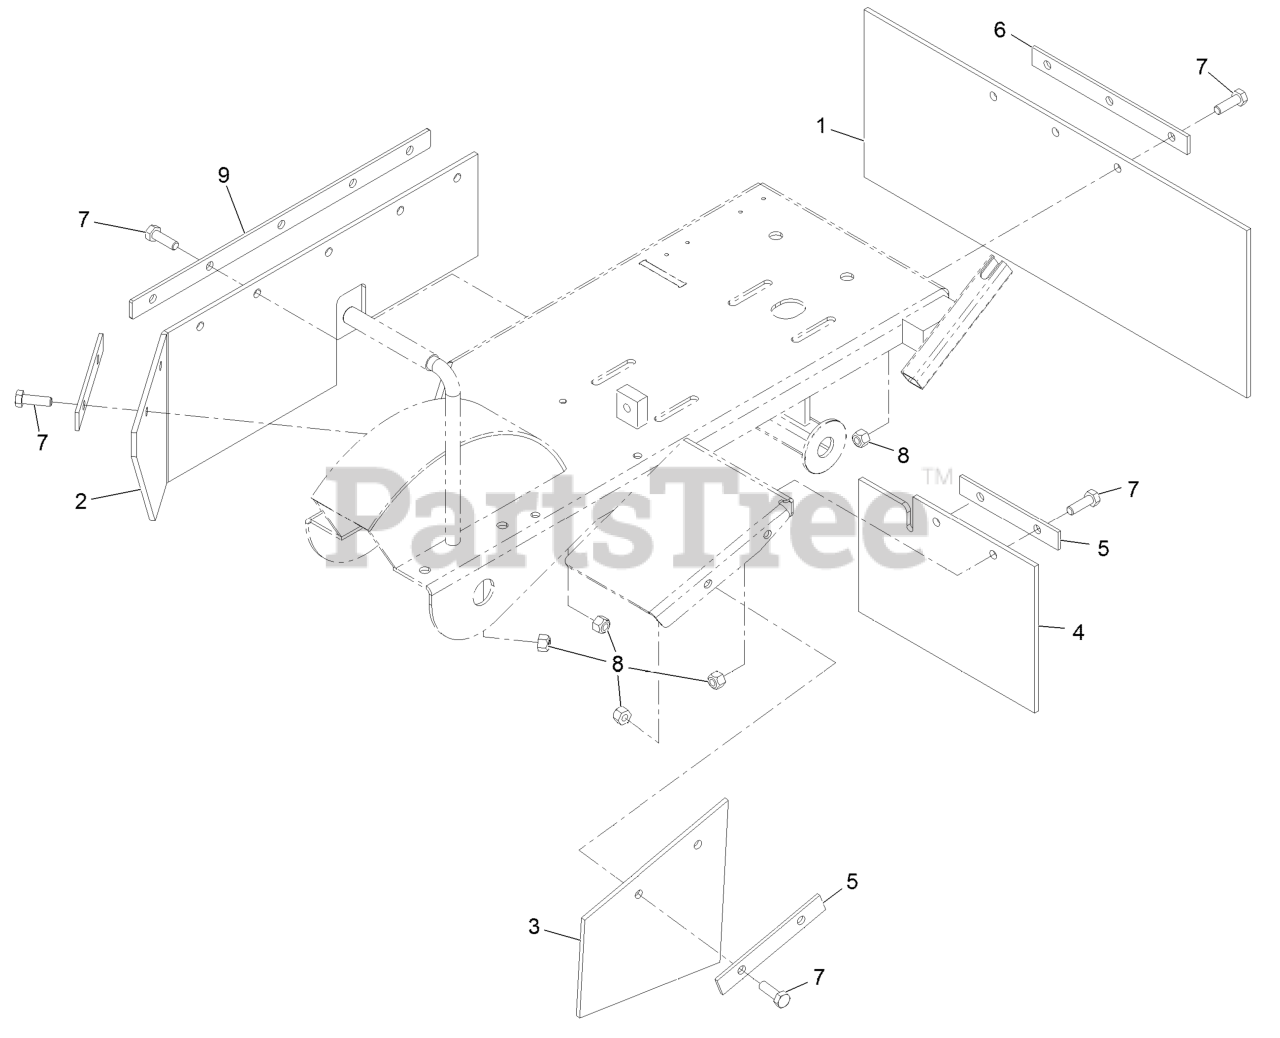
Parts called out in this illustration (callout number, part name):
1	FLAP-REAR
2	FLAP-RIGHT
3	FLAP-WING
4	FLAP-WING, REAR
5	PLATE-MOUNTING, FLAP
7	SCREW-HH
8	NUT-LOCK, NI
9	PLATE-MOUNTING, FLAP
